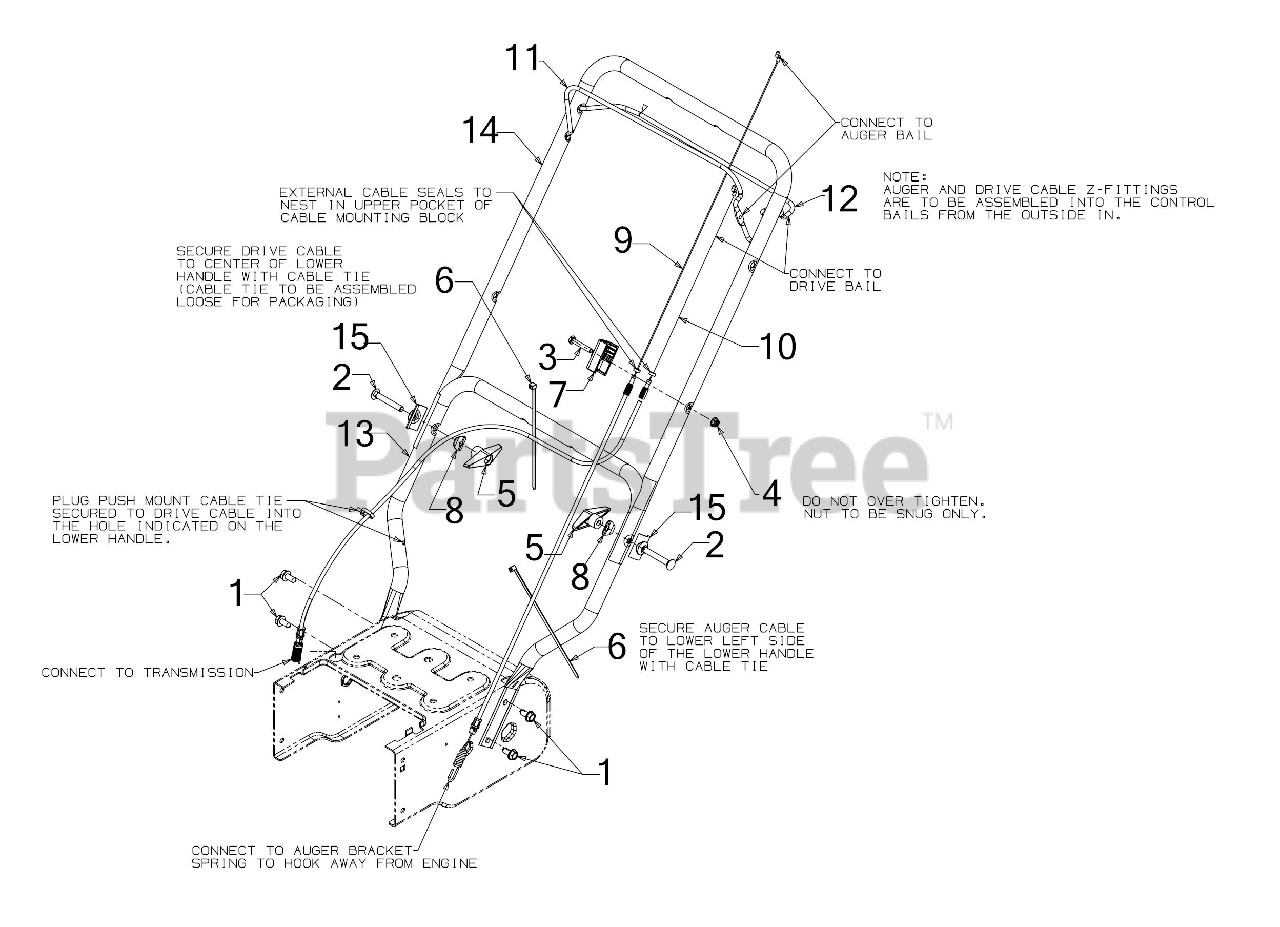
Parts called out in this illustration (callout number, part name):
1	SCREW 5/16-18 x .750
2	SCRE W5/16-18 x 2.25 GR5
3	SCREW 1/4-20 x 1.50 GR.5
4	FLANGE LOCK NUT
5	WING NUT KNOB
6	7" CABLE TIE
7	CABLE MOUNT
8	SADDLE WASHER
9	AUGER CLUTCH CABLE
10	TRANSMISSION CLUTCH CABLE
12	DRIVE BAIL
13	LOWER HANDLE
14	UPPER HANDLE
15	HANDLE TAB
